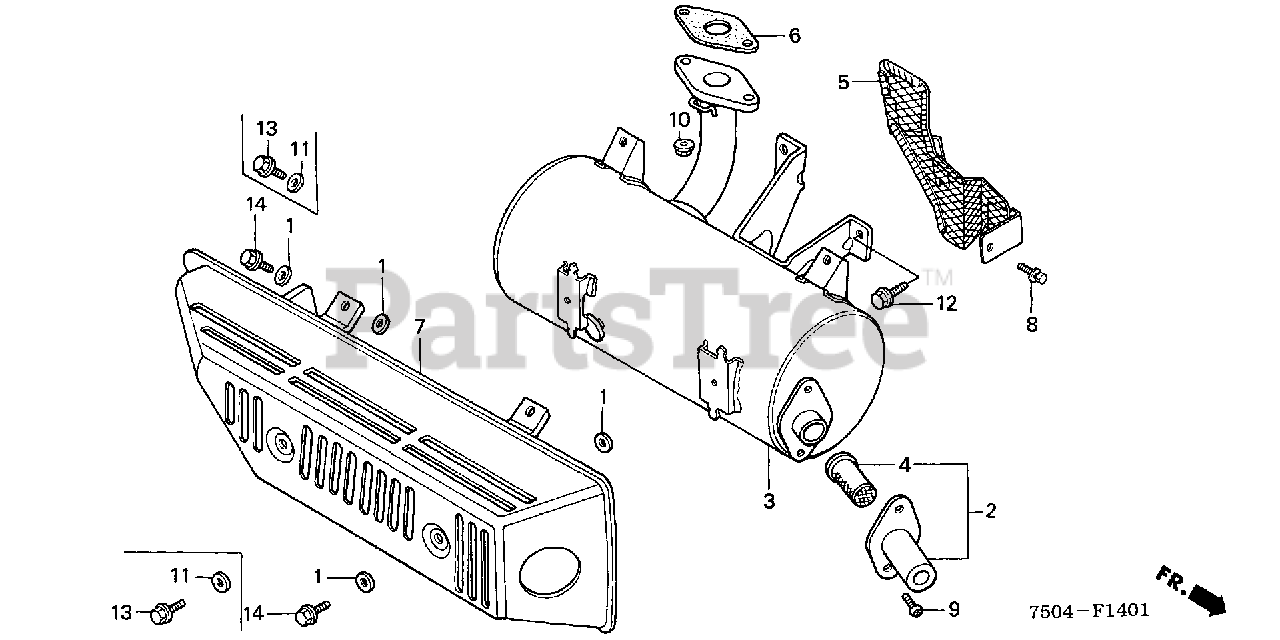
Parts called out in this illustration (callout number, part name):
2	CAP SET, ARRESTER
4	ARRESTER, SPARK
5	SCREEN, EX. COVER
6	GASKET, MUFFLER
7	COVER, HOOD SIDE
8	BOLT-WASHER (6X32)
9	SCREW, PAN (5X8)
10	NUT, FLANGE (8MM)
11	WASHER, PLAIN (6MM)
12	BOLT, FLANGE (8X20)
13	BOLT, FLANGE (6X10)
